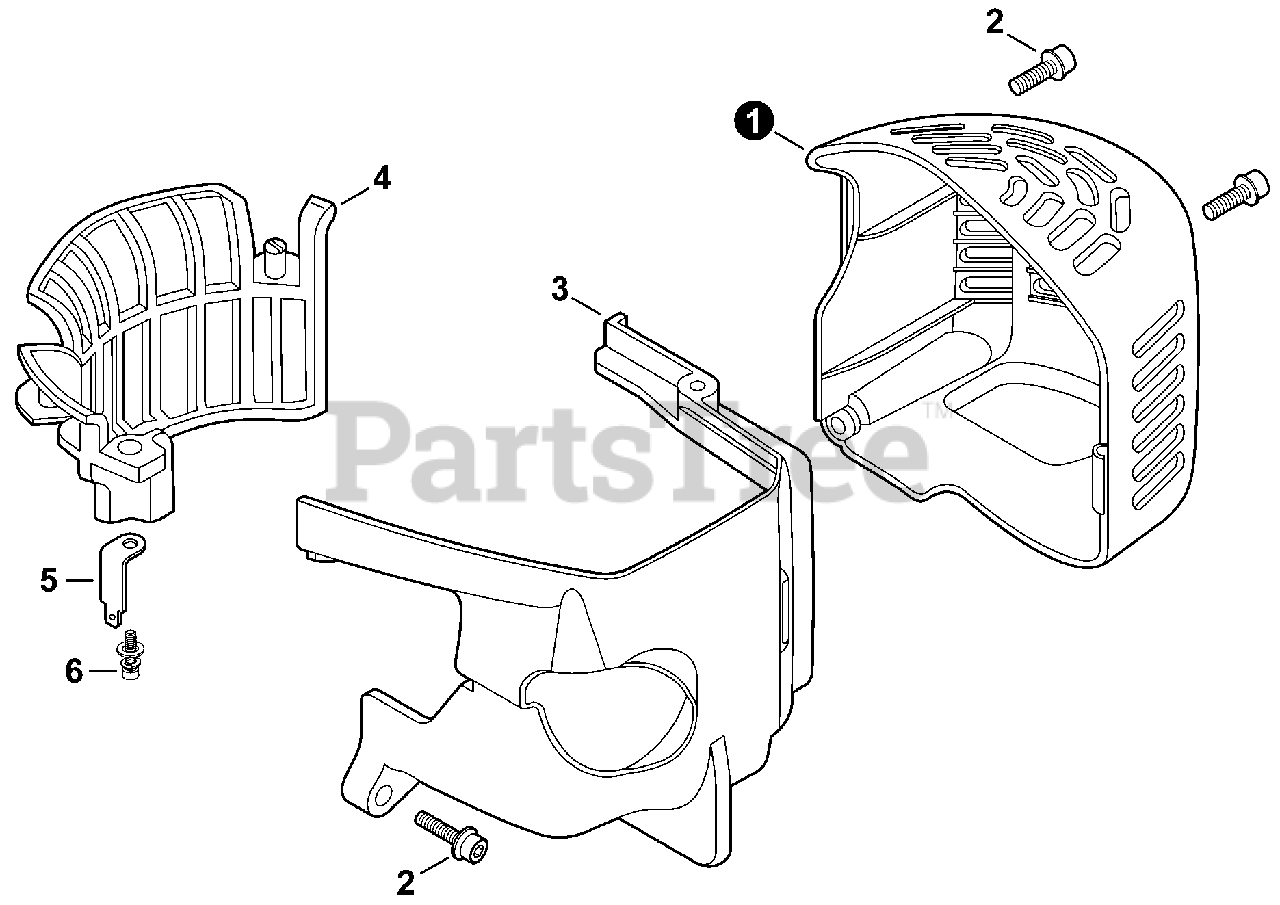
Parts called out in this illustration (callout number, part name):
1	COVER, MUFFLER
2	BOLT 5×16
3	COVER, ENGINE
4	SHIELD, DEBRIS
5	CONNECTOR
6	BOLT 5×16
